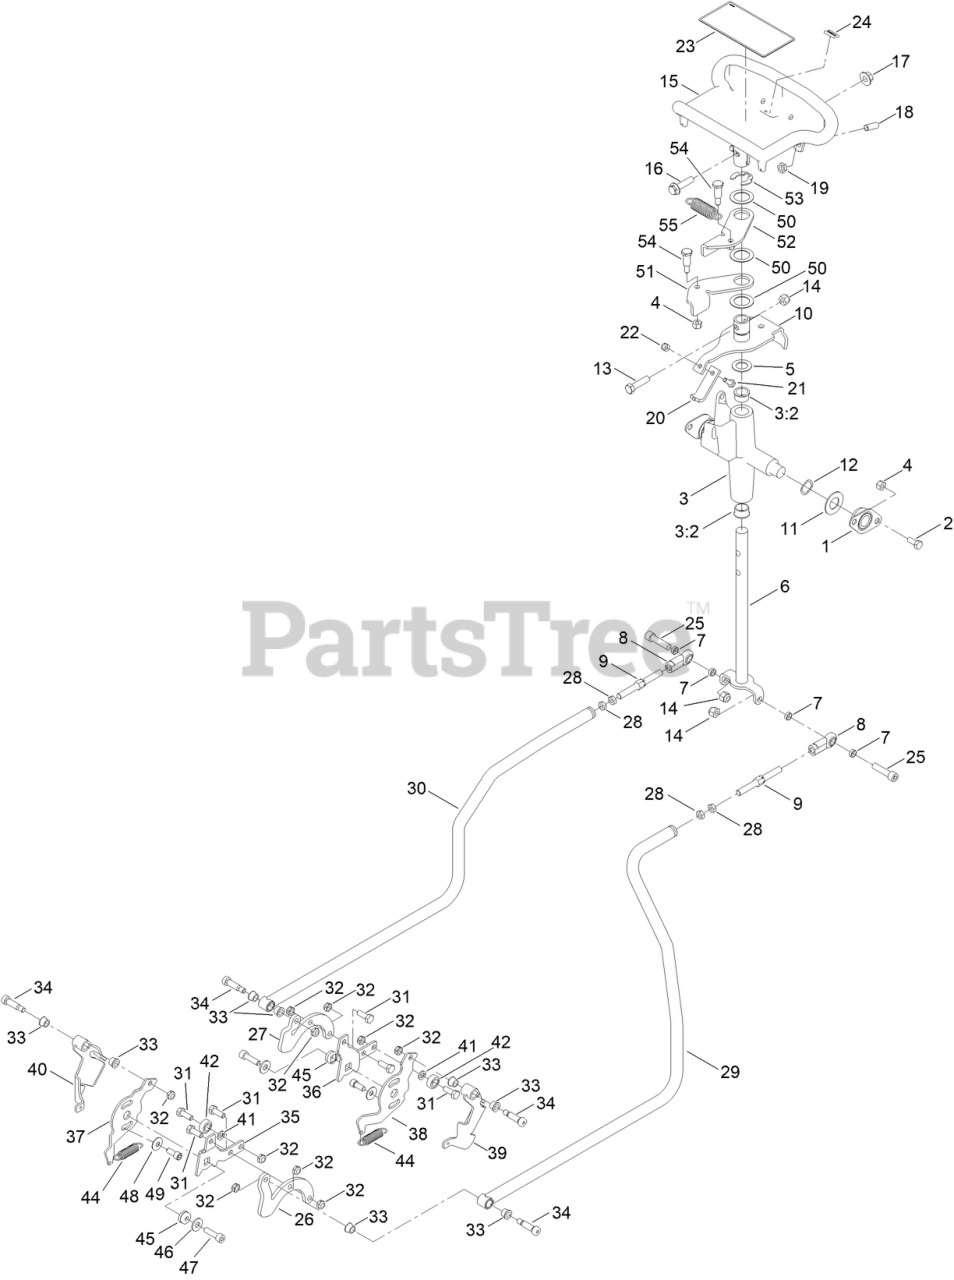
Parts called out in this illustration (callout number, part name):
1	BEARING
2	SCREW-HH
3	CONTROL SUPPORT ASM
3:2	BEARING-FLANGE
4	NUT-LOCK, NI
5	WASHER-THRUST
6	ROD-DRIVE
7	SPACER-PLATE, RETAINING
8	JOINT-BALL END, LH
9	LINK-CONTROL, ADJUSTMENT
10	LEVER-PIVOT
11	WASHER-FLAT
12	WASHER-SPRING, WAVE
13	SCREW-HH
14	NUT-LOCK, NI
15	HANDLE-CONTROL [BLK-TXT]
16	SCREW-HHF
17	NUT-FLANGE
18	SCREW-SET
19	NUT-JAM
20	PLATE-NEUTRAL
21	SCREW-HH
22	NUT-LOCK, NI
23	DECAL-TRACTION
24	DECAL
25	SCREW-HSH
26	PLATE-CONTROL, LH
27	PLATE-CONTROL, RH
28	NUT-HJ
29	ROD-CONTROL, LH
30	ROD-CONTROL, RH
31	SCREW-HH
32	NUT-LOCK, NI
33	BUSHING-FLANGE
34	BOLT-SHOULDER
35	PLATE-ARM, RETURN, LH
36	PLATE-ARM, RETURN
37	PLATE-BASE, LH
38	PLATE-BASE, RH
39	PIVOT-RH
40	PIVOT-LH
41	WASHER-LOCK
42	BEARING-BALL
44	SPRING-EXTENSION
45	LOCK-TRUNION
46	WASHER-FLAT
47	SCREW-HSH
48	WASHER-BELLEVILLE
49	SCREW-HSH
50	WASHER-PLAIN
51	LEVER-RETURN, RH
52	LEVER-RETURN, LH
53	RING-RETAINING
54	SCREW-SHOULDER
55	SPRING-EXTENSION
